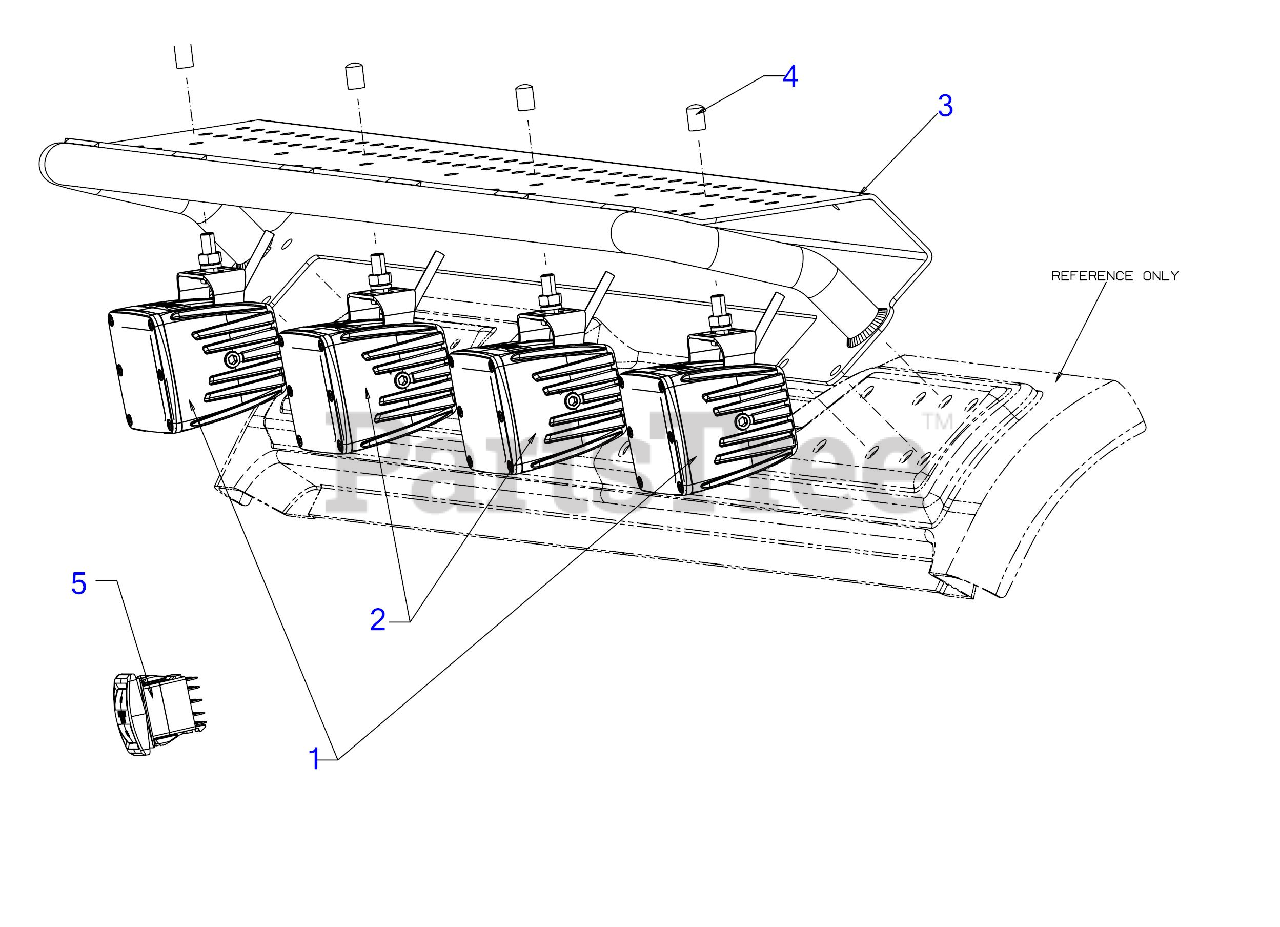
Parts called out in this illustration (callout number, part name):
1	LED CUBE FLOOD LIGHT
2	LED CUBE SPOT LIGHT
3	LIGHT BAR PROTECTOR
5	ROCKER SWITCH FOR LIGHT BAR
